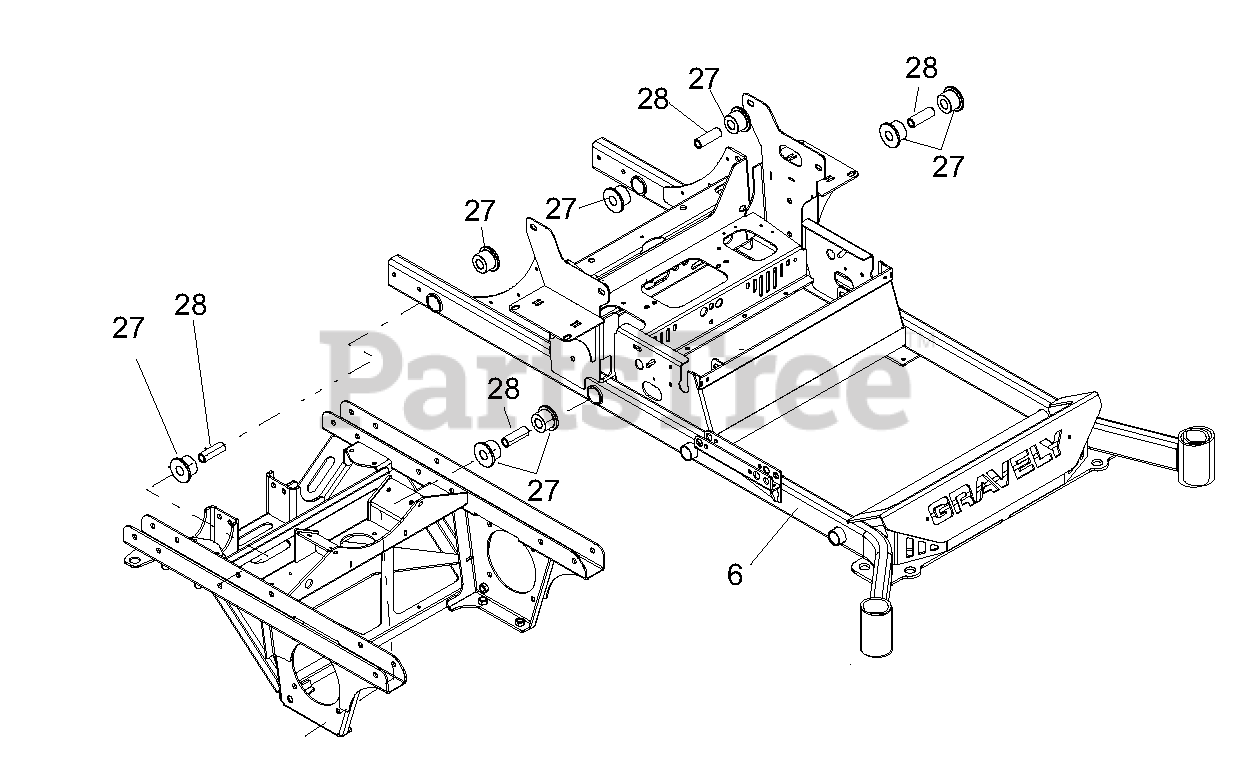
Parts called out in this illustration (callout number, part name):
6	WLDMT, PT400 MAIN FRAME (992236)
27	BUSHING, FLANGE .75X1.51X1.13X2.0 URE
28	BUSHING, SHEAVE .50X.75X2.23
